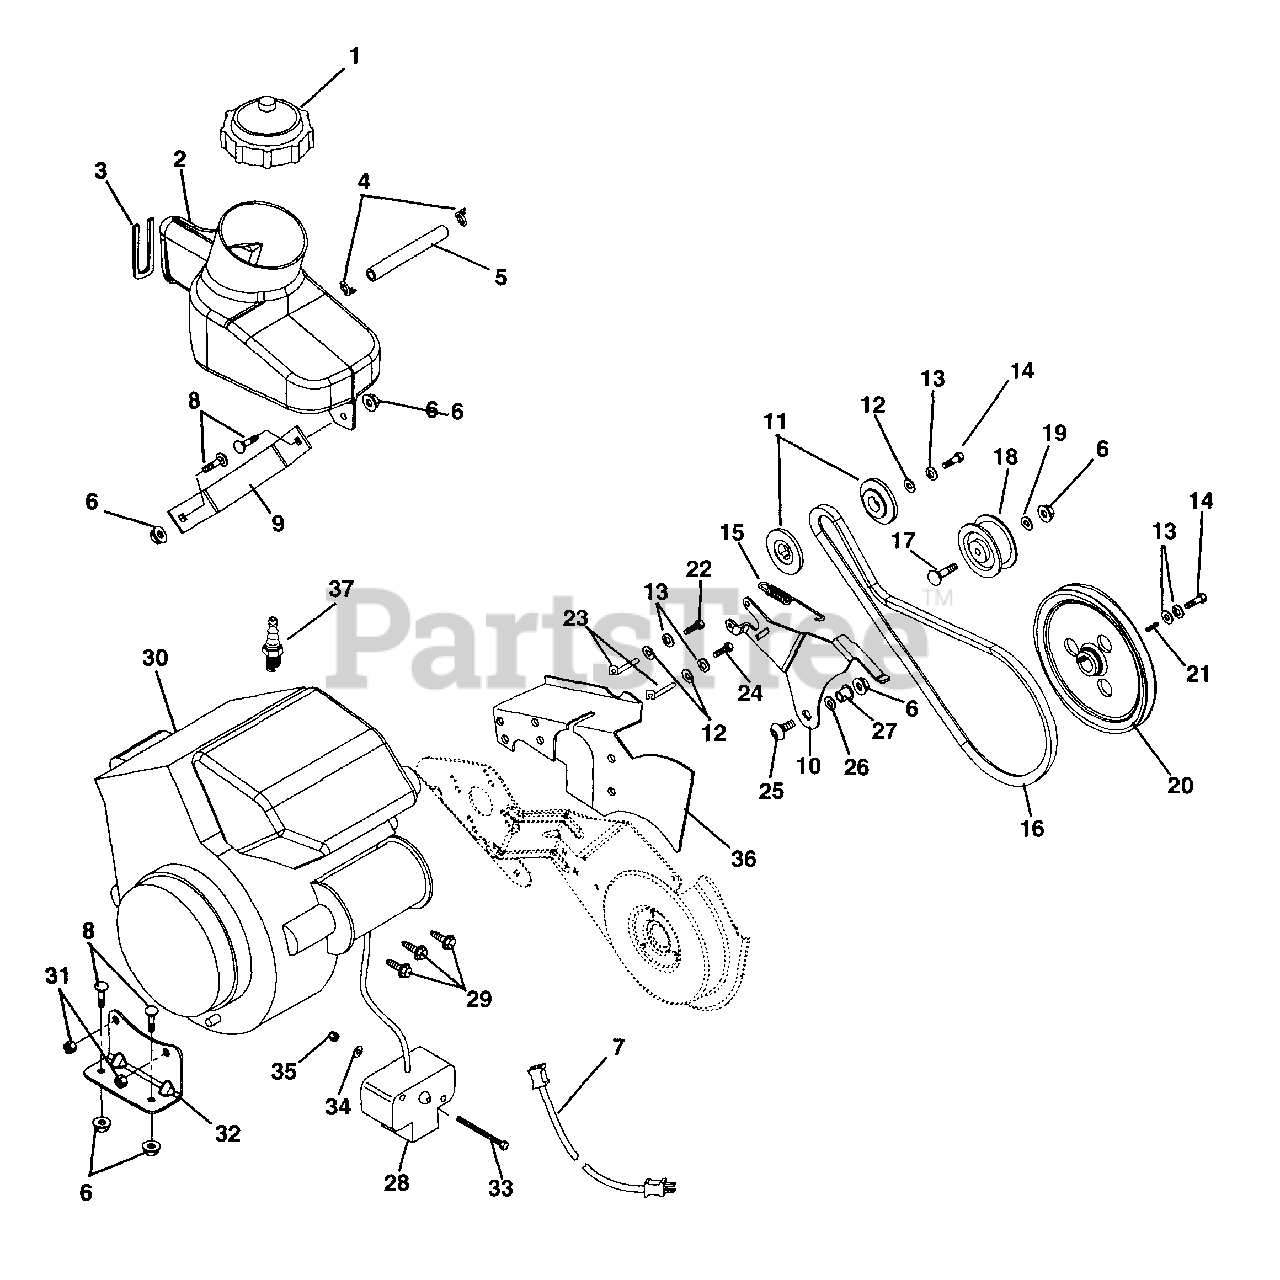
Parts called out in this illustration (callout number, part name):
1	CAP-FUEL
2	TANK, FUEL
3	TAPE FOAM,NEOPRENE
4	CLAMP-HOSE WIR.490/.510X.092#8
5	GAS LINE 1/4" I.D. X 9.5
5	GAS LINE HOSE 1/4 X 11"
6	NUT-LK-FLG .250-20 PL BLK
7	CORD, EXTENSION
8	@BLT-RDHDSQNK .25-20X.75 G5YZ
9	BRKT-FUEL TANK MTG
10	ARM-IDLER
11	PLY-DRIVE 3LX 1.80 DIA
11	PLY-DRIVE 3LX 1.52 DIA
12	@WSHR-FL-STL.38X.875X.083 YWZC
13	@WSHR-LK .31X.078 REG YWZC
14	BLT-HEX .31-24X.75 YWZC GR5
15	SPRING, EXTENSION
16	V-BELT, 3L-RAW EDGE
17	@BLT-RDHDSQNK .25-20X1.25 G5YZ
18	IDLER-FLAT 1.75 X .27 DAYCO
19	WSHR-FL-STL .281X1.000X.063
20	PLY-V 5.50X.671 W/KEY "A"
21	KEY-SQ .188X.75X.188
22	@BLT-HEX .31-18X.75 GR5 YWZC
23	FINGER-BELT
24	@BLT-HEX .31-18X1.00 GR5 YWZC
25	SCR-MCH .25-20X.75 TXTR YWZC
26	WSHR-FL-STL .505X.875X.024 YWZ
27	BSHG-FLG .265X.437X.250X.750
28	MOTOR-STARTING
29	SCR-HFWH-TX-SEMS .25-20X.49 TE
30	ENGINE, TH139SA 5HP 2CY TEC
30	ENGINE-HSK600 3HP 2-CY (EPA-C)
31	@NUT-LK-CTR .31-18 YWZC
32	BRKT-ENGINE MTG
33	@SCR-MCH 8-32X2.75 HWH YWZC
34	@WSHR-FL-STL.219X.50X.049 YWZC
35	@NUT-LK-NYL 8-32 W/INSTR YWZC
36	BAFFLE-BELT PROTECTIVE
37	PLUG, SPARK
